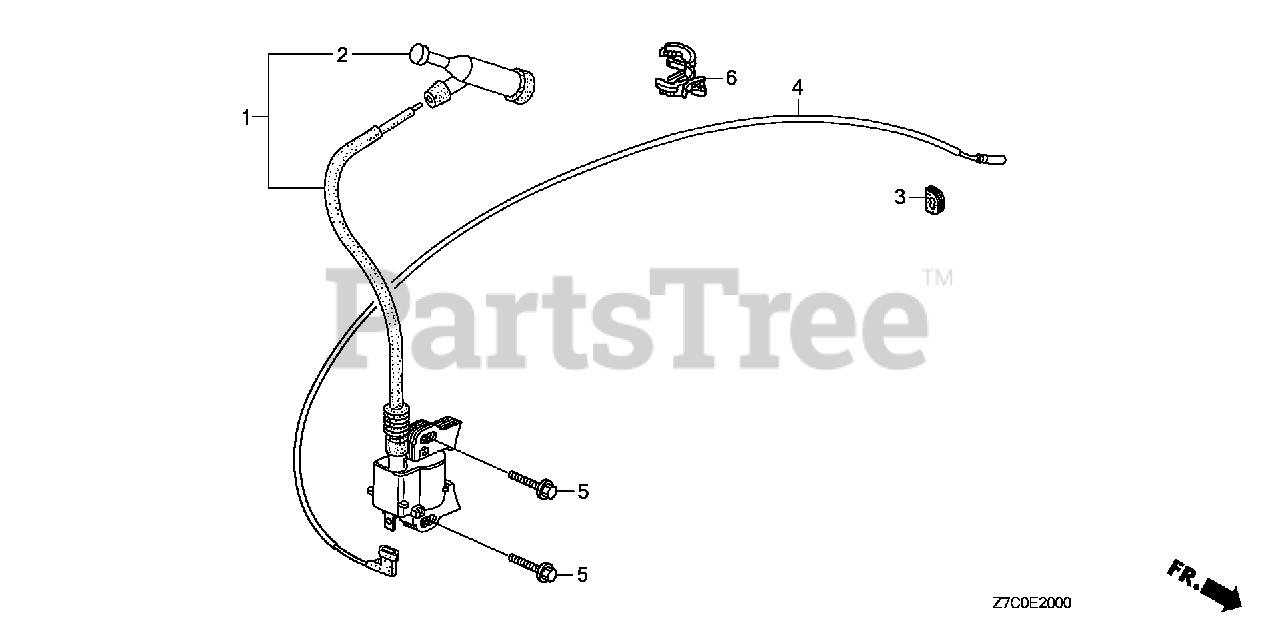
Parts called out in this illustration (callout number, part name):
1	COIL ASSY., IGNITION
2	CAP ASSY., NOISE SUPPRESSOR (TEC)
3	GROMMET, WIRE
4	WIRE, STOP SWITCH (370MM)
5	BOLT, FLANGE (6X28) (CT200)
6	CLIP, HARNESS
